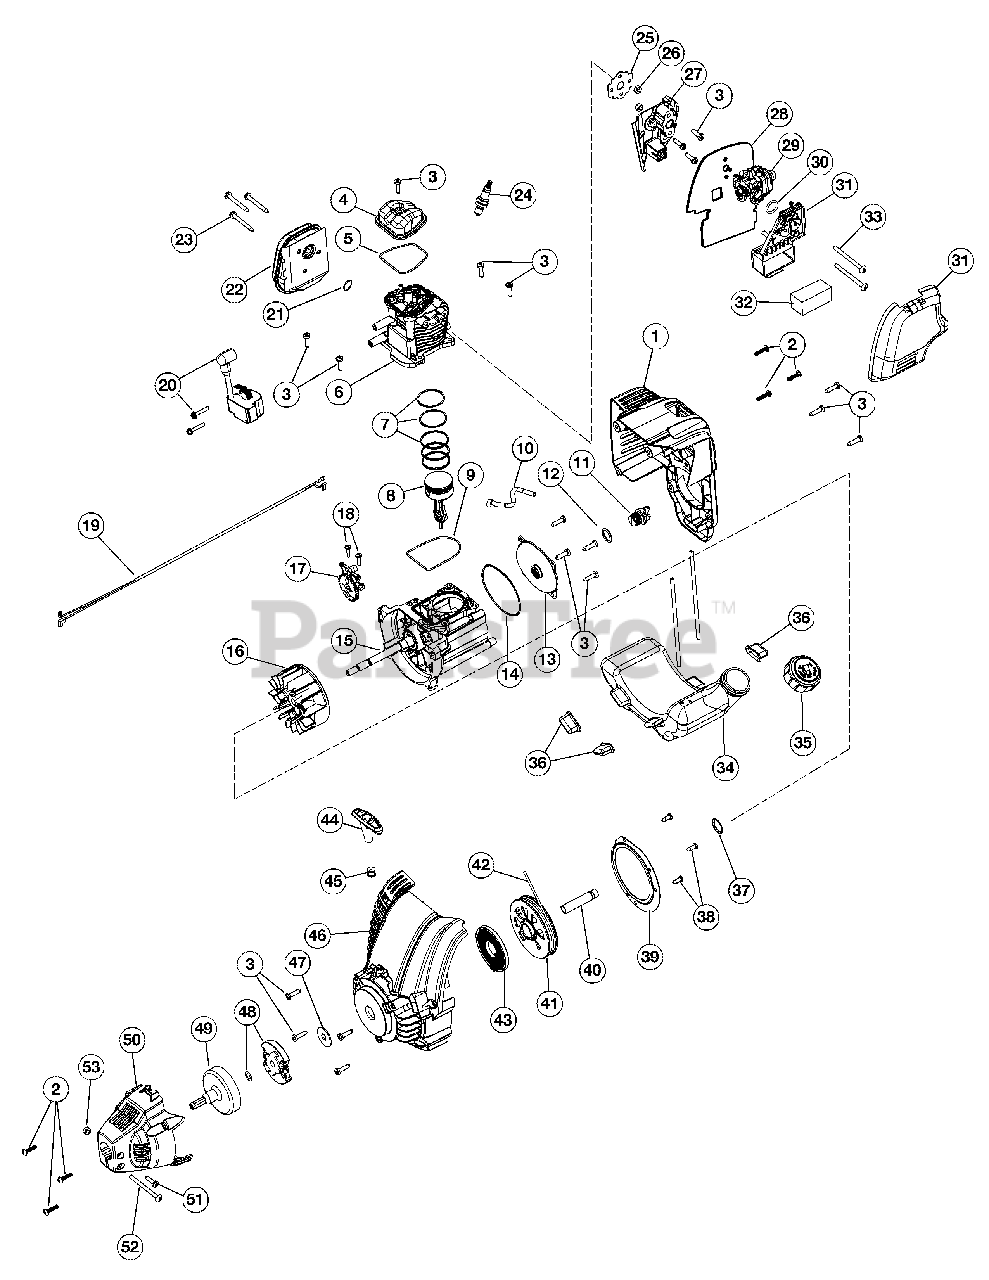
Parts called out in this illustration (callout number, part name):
1	Engine Cover Assembly
2	Cover Screw
3	Screw
4	Rocker Cover
5	Rocker Cover O-Ring
6	Cylinder Assembly
7	Piston Ring Assembly
8	Piston Assembly
9	Cylinder O-Ring
10	Breather Hose
11	Oil Plug
12	Oil Plug O-Ring
13	Crankcase Cover
14	Crankcase Cover O-ring
15	Crankcase Assembly
16	Flywheel Assembly
17	Cam Bracket Assembly
18	Cam Bracket Screw
19	Lead Wires
20	Module Assembly
21	Muffler Gasket
22	Muffler Assembly
23	Muffler Screw
24	Spark Plug
25	Insulator Gasket
26	Nut
27	Insulator
28	Carburetor Gasket
29	Carburetor w/Primer
31	Air Cleaner Cover Assembly
32	Air Filter
33	Screw
34	Fuel Tank Assembly w/Fuel Lines
35	Fuel Cap
36	Fuel Tank Pads
37	Push Nut
38	Pressure Plate Screw
39	Pressure Plate
40	Spacer
41	Starter Assembly
43	Recoil Spring
44	Handle
45	Rope Guide
46	Starter Housing Assembly
47	Washer
48	Clutch & Clutch Washer
49	Clutch Drum
50	Clutch Cover
51	Anti-Rotation Screw
52	Clamp Screw
53	Nut
